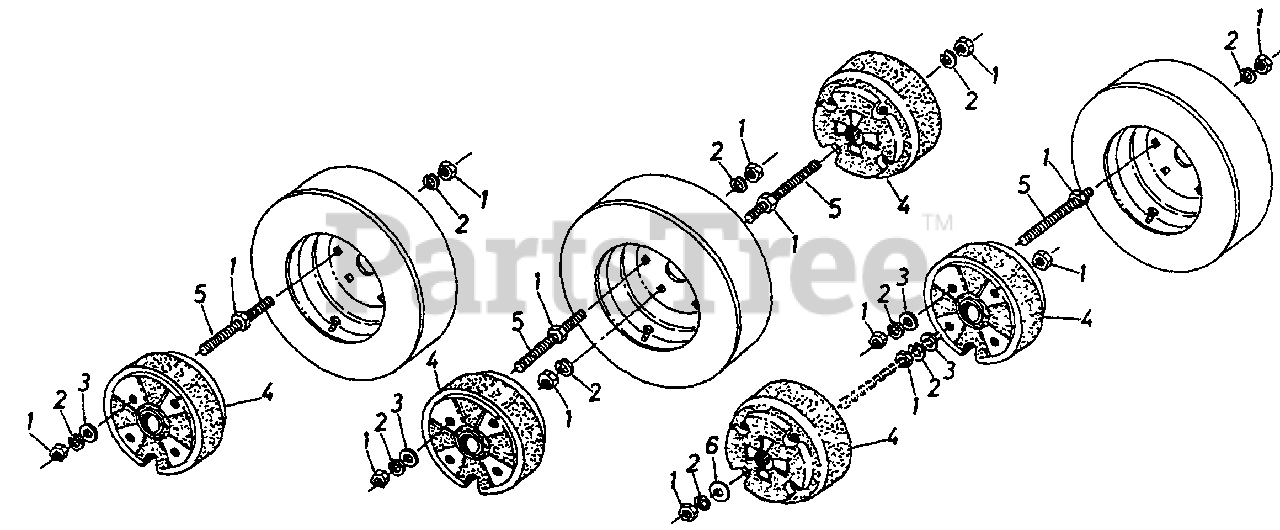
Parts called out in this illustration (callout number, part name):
1	Hex Nut 1/2-13 Thd.
2	Lock Wash. 1/2" I.D.
3	Fl-Wash .53" I.D. x.93" O.D.
4	Wheel Weight
5	Rod Threaded 1/2-13 x 9.5" Lg.
6	Fl-Wash .5" I.D. x 2.0" O.D.
